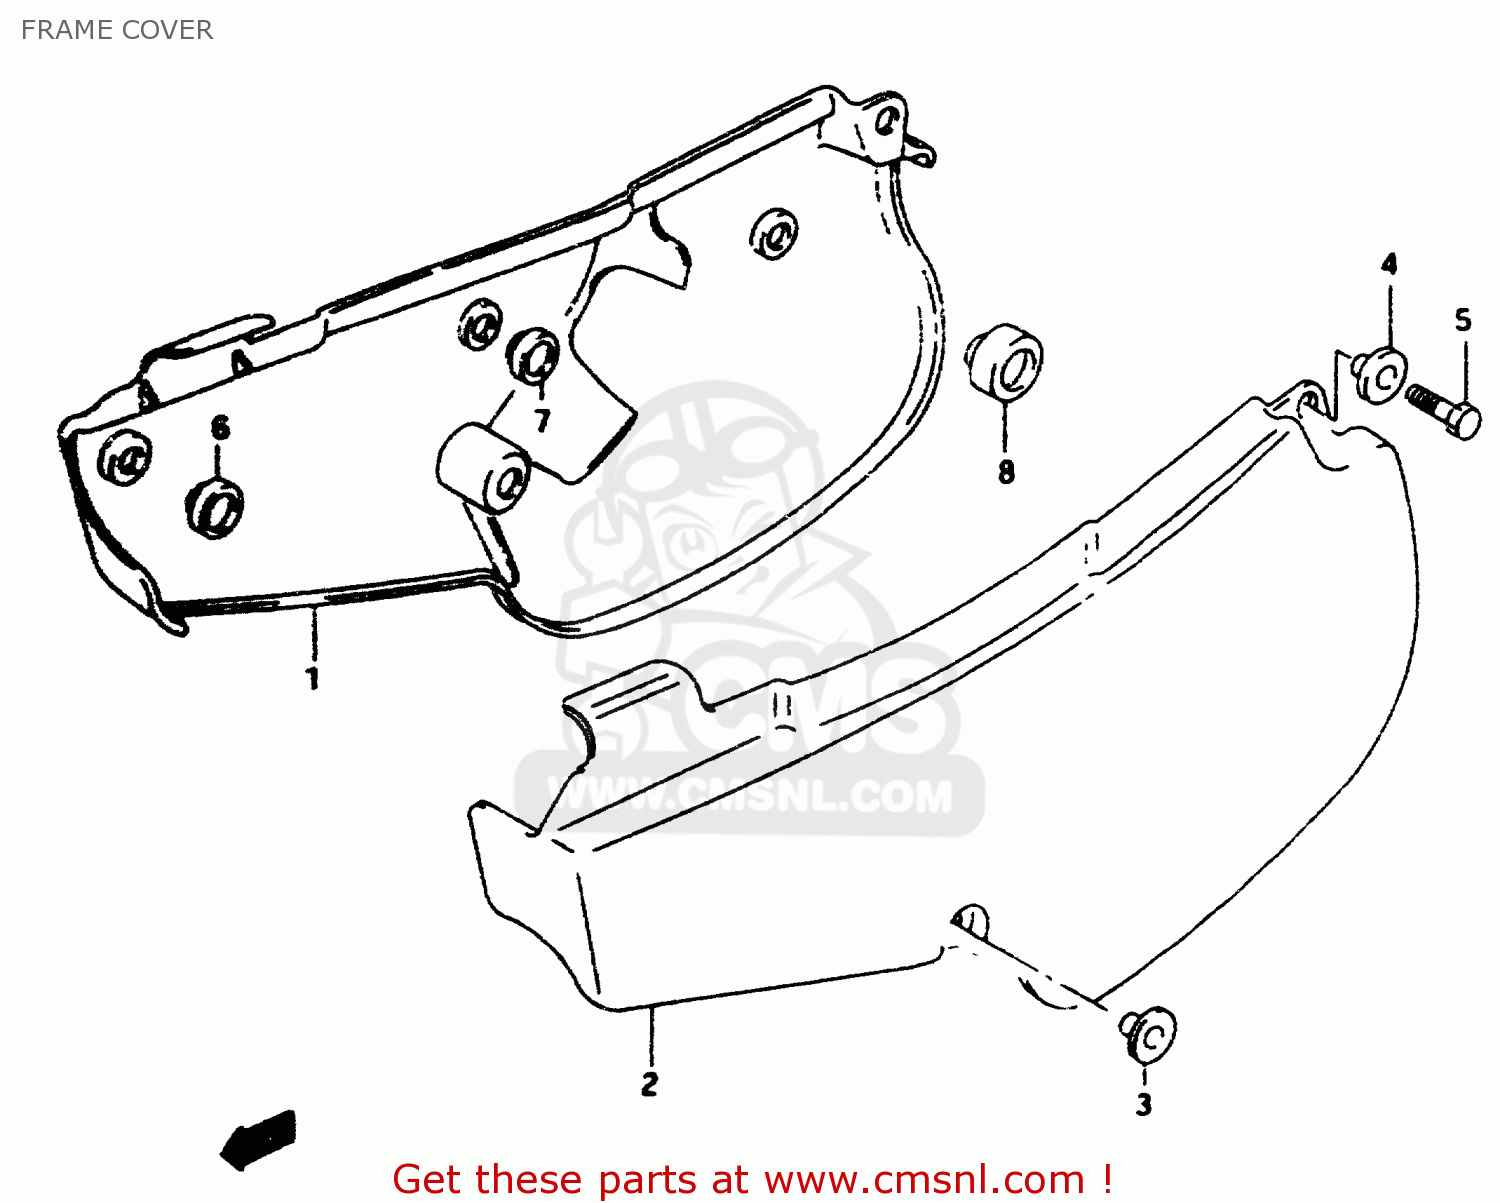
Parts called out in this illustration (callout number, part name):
1	COVER,SIDE,R(WHITE)
2	COVER,SIDE,L(WHITE)
3	WASHER
4	WASHER
5	SCREW
6	CUSHION
7	CUSHION
8	CUSHION
